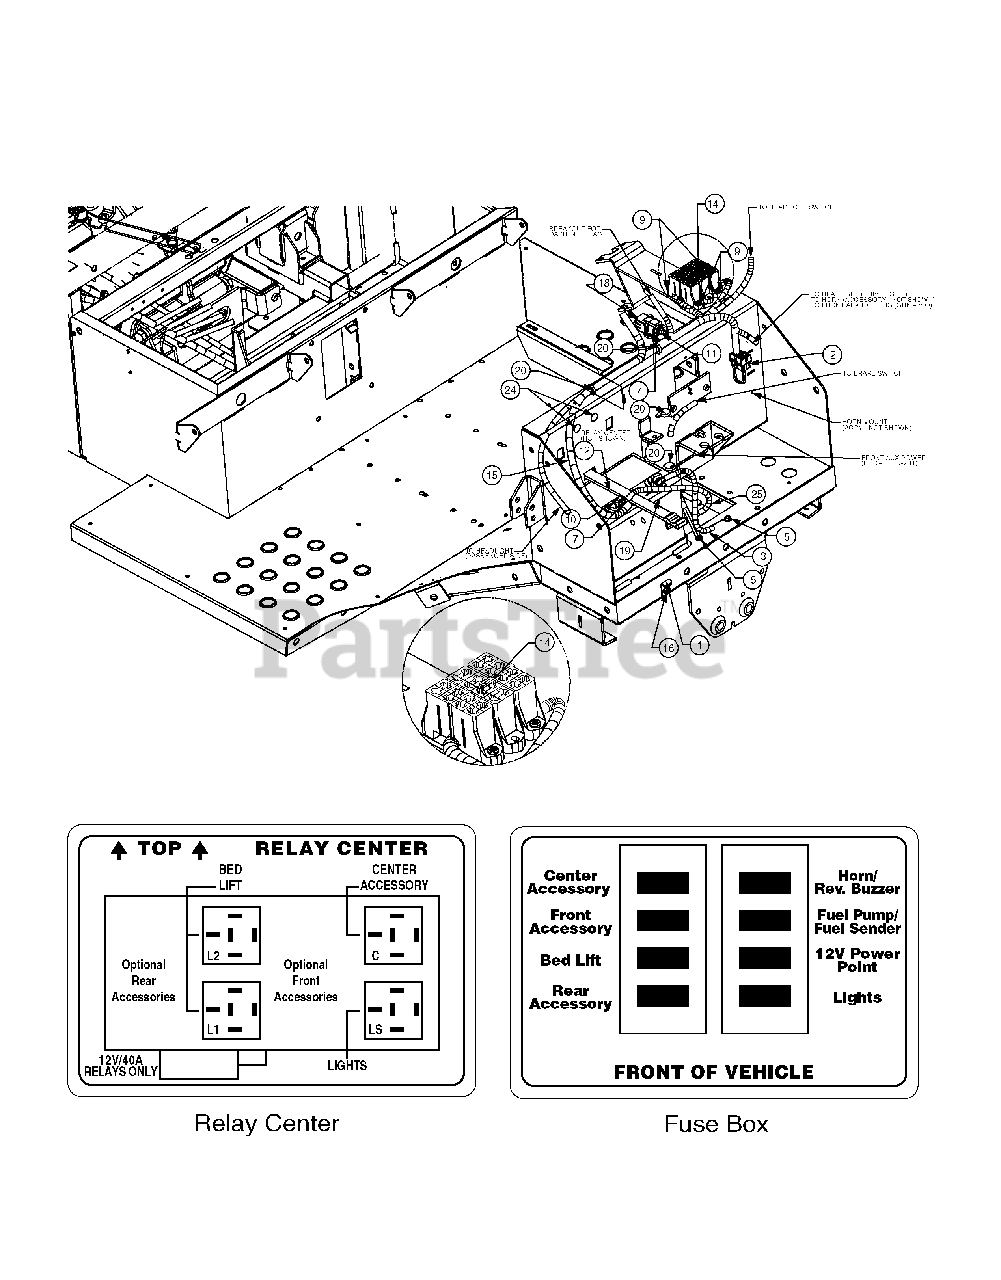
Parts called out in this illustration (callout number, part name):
1	Retainer Hook Bracket
2	Starter Harness Assembly
3	Motor Ground Harness Assembly
4	Screw, 1/4-20 x .50
5	Self-tapping Screw, 1/4-20 x 0.500
7	Hex Carriage Screw, 1/4-20 x.75
9	Screw, #10-24 x 0.75
10	Hex Sems Nut, 1/4-20
11	Protective Cover
12	Battery Strap
14	5 Amp Fuse
15	Utility Main Harness
16	Motor Harness
18	Switch
19	Battery
20	Cable Tie, .19 x 8.39 Tree Mount
24	Retainer Clip,.250 x.267
25	Conv. Conn. Assembly
